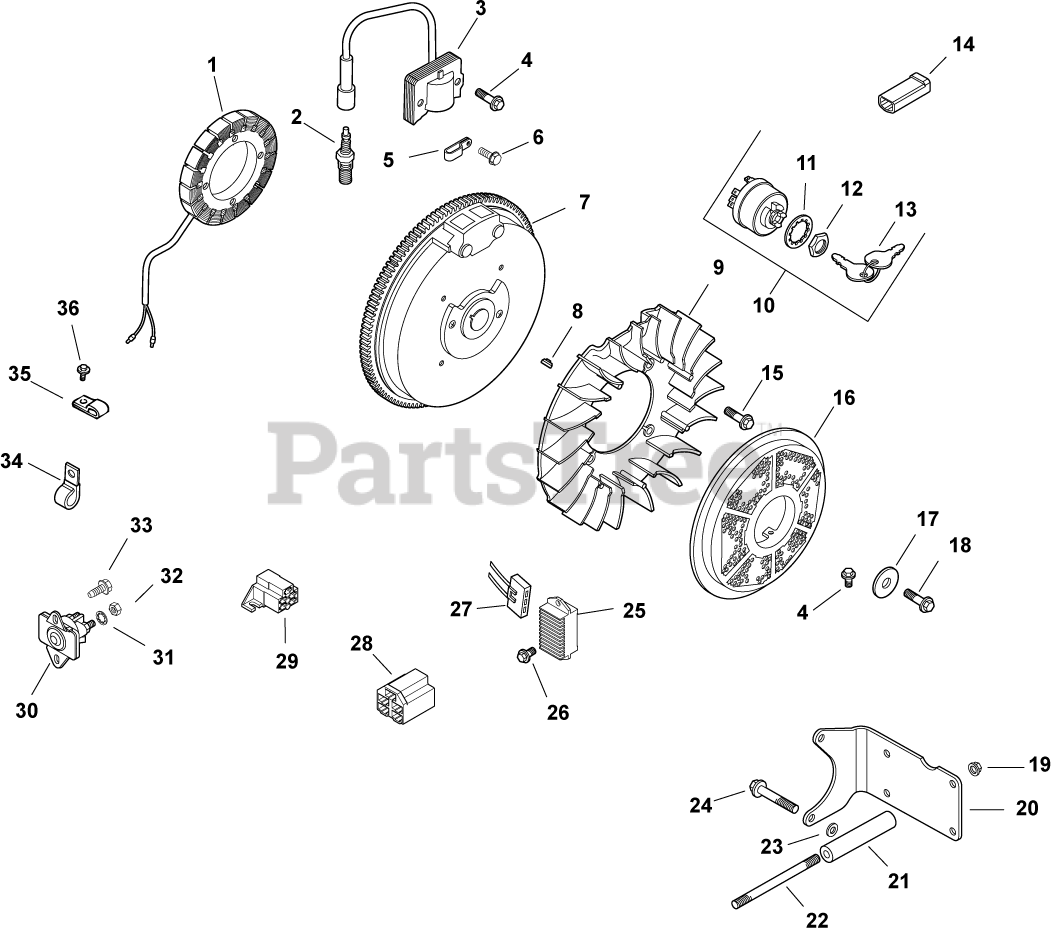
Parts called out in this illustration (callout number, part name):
1	KIT, 25 AMP STATOR ASSY.
2	PLUG, SPARK (PRO SERIES)
3	MODULE, IGNITION
4	SCREW, FLG THD FRM M5X.8X20-(#25086399S)
6	SCREW, FLG THD FRM M5X.8X10
8	KEY, 3/16" X 5/8"
9	FAN - DISCONTINUED
10	SWITCH ASSY, KEY (KM)-USE 25 099 32-S
11	WASHER, INTERNAL TOOTH
12	NUT, KEY SWITCH
13	KEY, SET -USE 48 340 01-S
14	CONNECTOR (1 CONTACT)
15	BOLT, SHOULDER
16	SCREEN, GRASS
17	WASHER, FLAT 13/32"
18	SCREW, FLG M10X1.5X45 - (#25086361S)
19	NUT, FLG M8X1.25
20	BRACKET, FUEL TANK
22	STUD, M8X1.25X133-USE 25 755 54-S
23	WASHER, FLAT 11/32"
24	SCREW, FLG M8X1.25X45
25	REG/RECTIFIER (20/25 AMP)-USE 25 403 20-
26	SCREW, FLG M6X1.0X16
27	CONNECTOR, BODY (KM)-USE 25 155 41-S
28	CONNECTOR
29	CONNECTOR
30	SOLENOID - WATERPROOF (KM)-USE 25 435 08
31	WASHER, INT TOOTH LOCK 1/4"
32	NUT, JAM 1/4-20 GRADE 2
33	SCREW,FLG THD FRM M6X1.0X16-(#25086397S)
34	CLIP, CABLE
35	CLIP, TUBE & WIRING (KM)
36	SCREW, THD FROM M5X0.8X30
